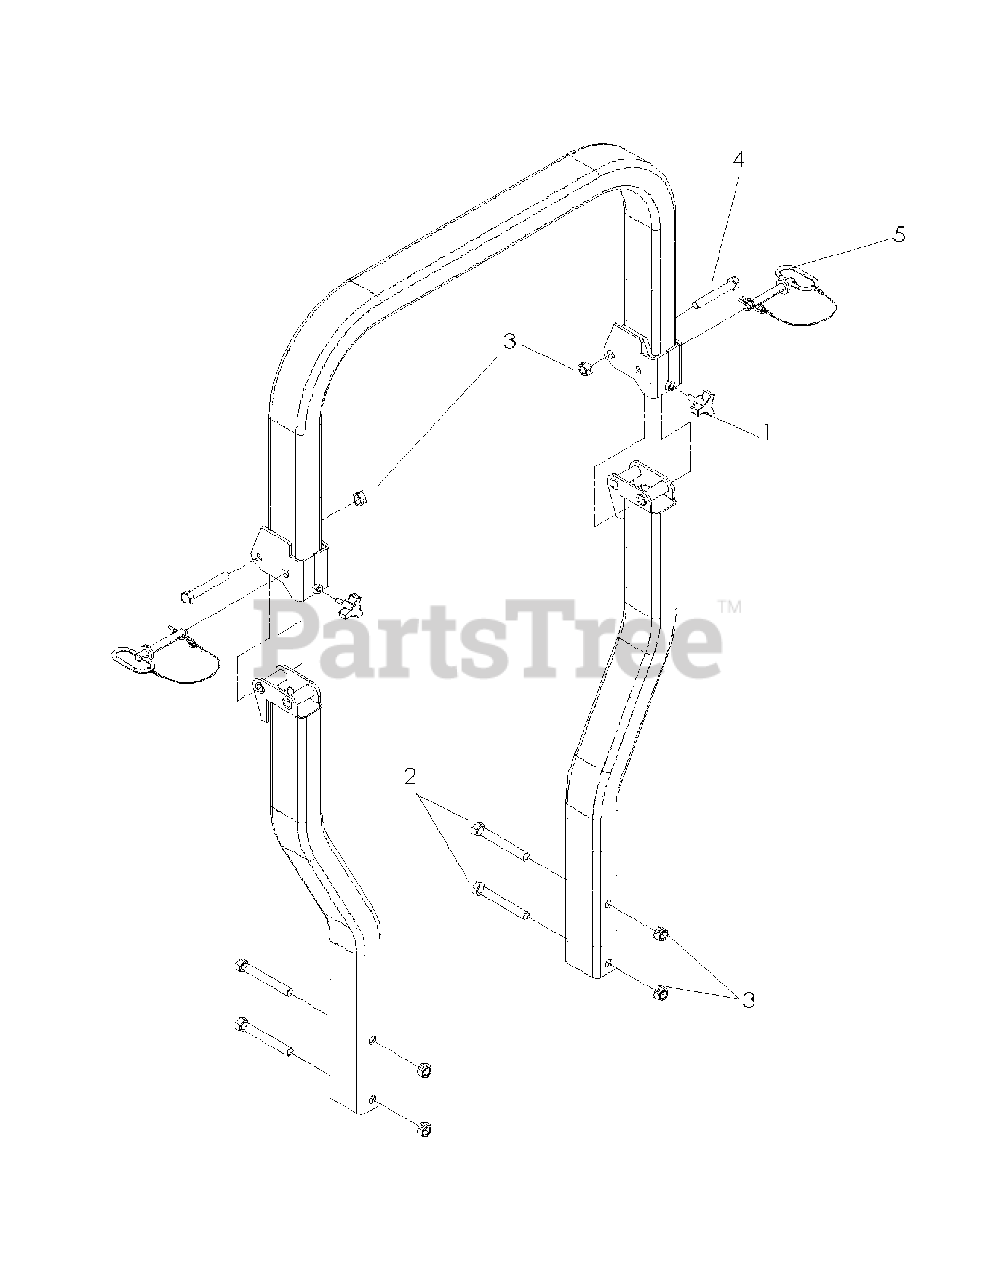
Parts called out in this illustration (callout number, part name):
1	KNOB W/STUD 3/8-16 X 1.5
2	HCS 1/2-13 X 4 GR 5 ZD
3	NUT 1/2-13 HEX CNTRLK GR 5 ZD
4	HCS 1/2C X 3 1/4
5	PIN, 1/2" W/LANYARD
